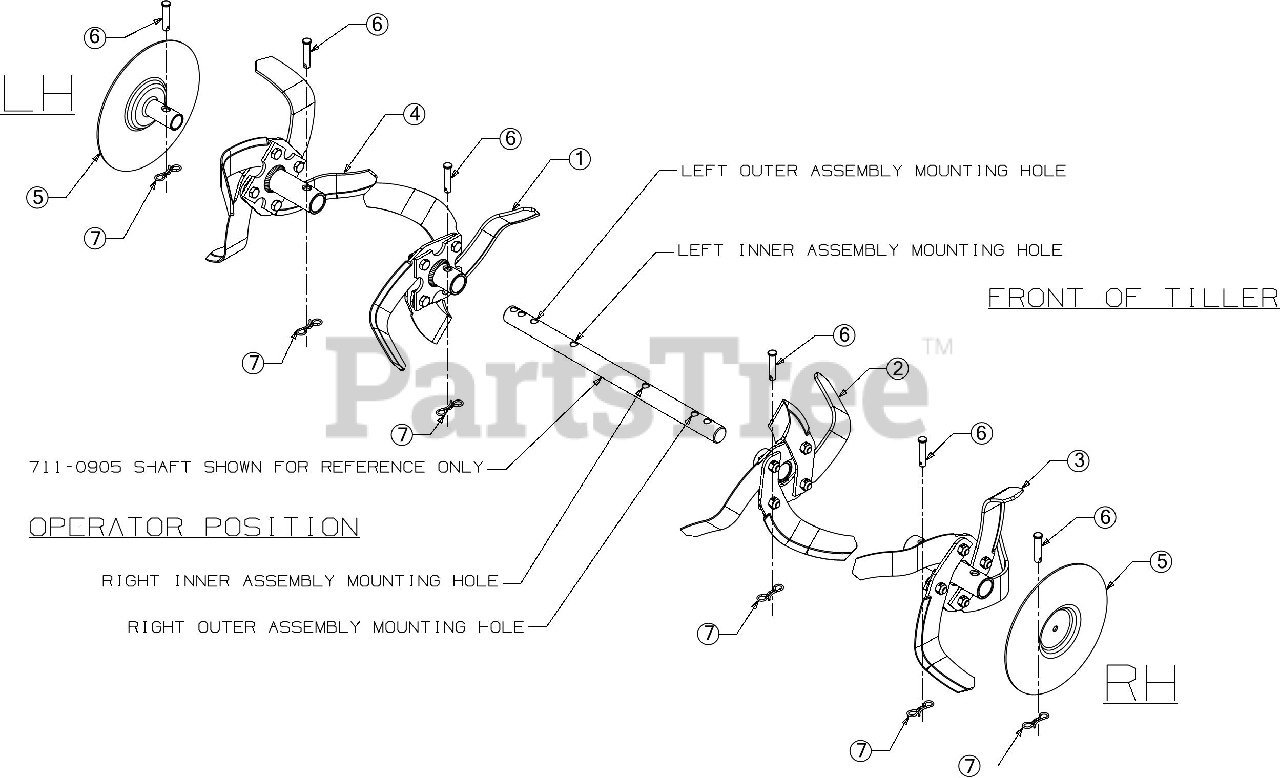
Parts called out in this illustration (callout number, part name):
1	BOLO TINE ASSEMBLY (INNER) (LH)
1	SCREW 3/8-16 X 1 GR5
1	LOCK NUT 3/8-16
2	BOLO TINE ASSEMBLY (INNER) (RH)
2	SCREW 3/8-16 X 1 GR5
2	LOCK NUT 3/8-16
3	TINE ASSEMBLY OUTER (RH)
3	SCREW 3/8-16 X 1 GR5
3	LOCK NUT 3/8-16
4	TINE ASSEMBLY OUTER (LH)
4	SCREW 3/8-16 X 1 GR5
4	LOCK NUT 3/8-16
5	OUTER DISC PLATE
6	CLEVIS PIN .375 X .1.75
7	PIN:COTTER
